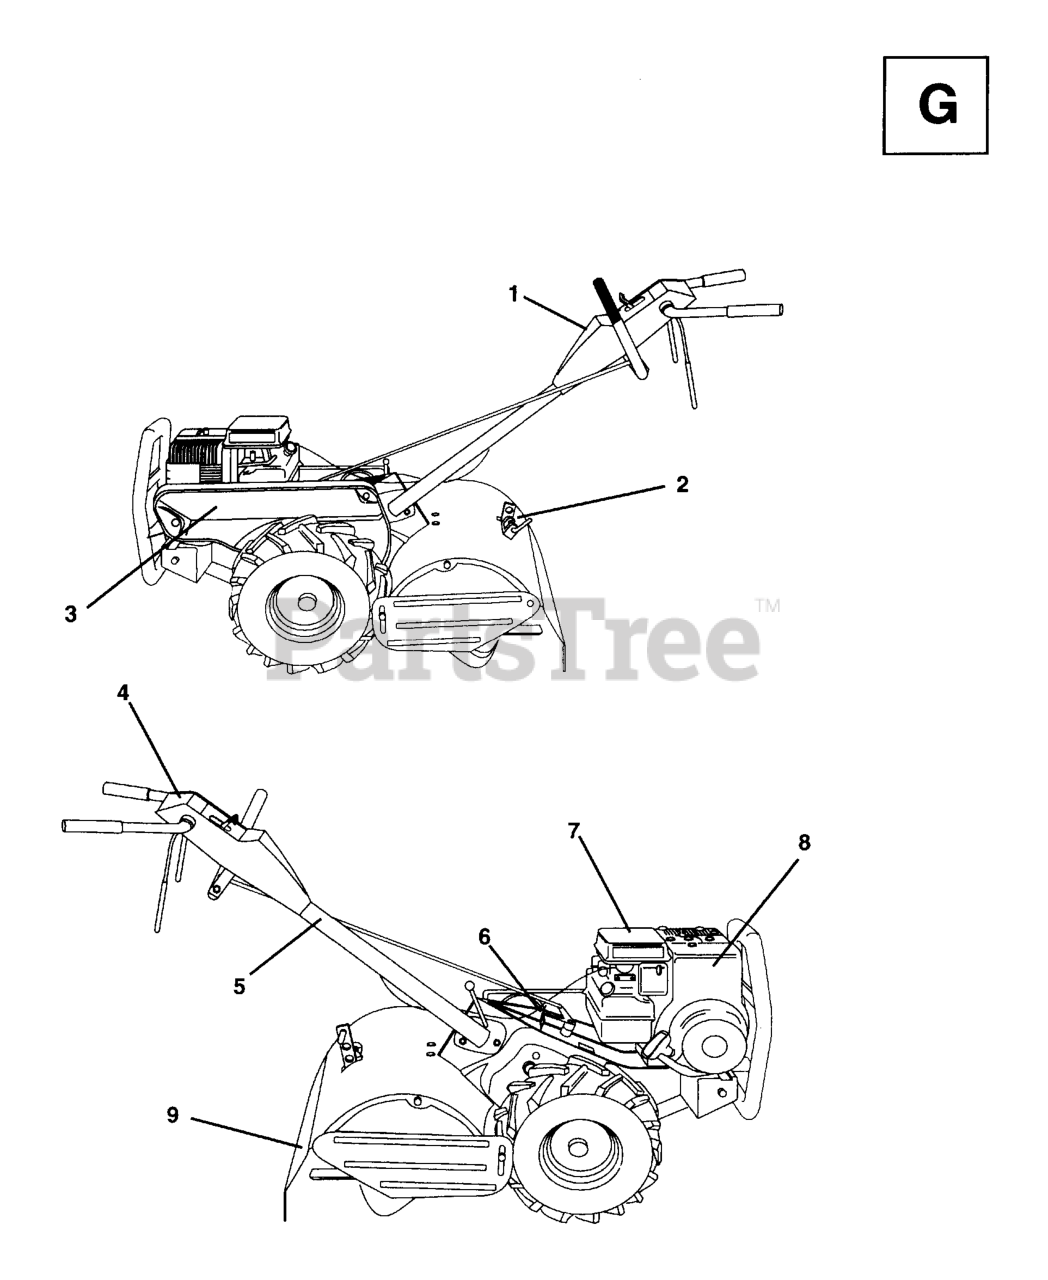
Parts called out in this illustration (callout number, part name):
1	DECAL CONTROL PANEL
2	DECAL TINE SHIELD
4	DECAL INST CONTROL PANEL
5	DECAL TI (2 2)
6	DECAL TI NLA
9	DECAL TI
